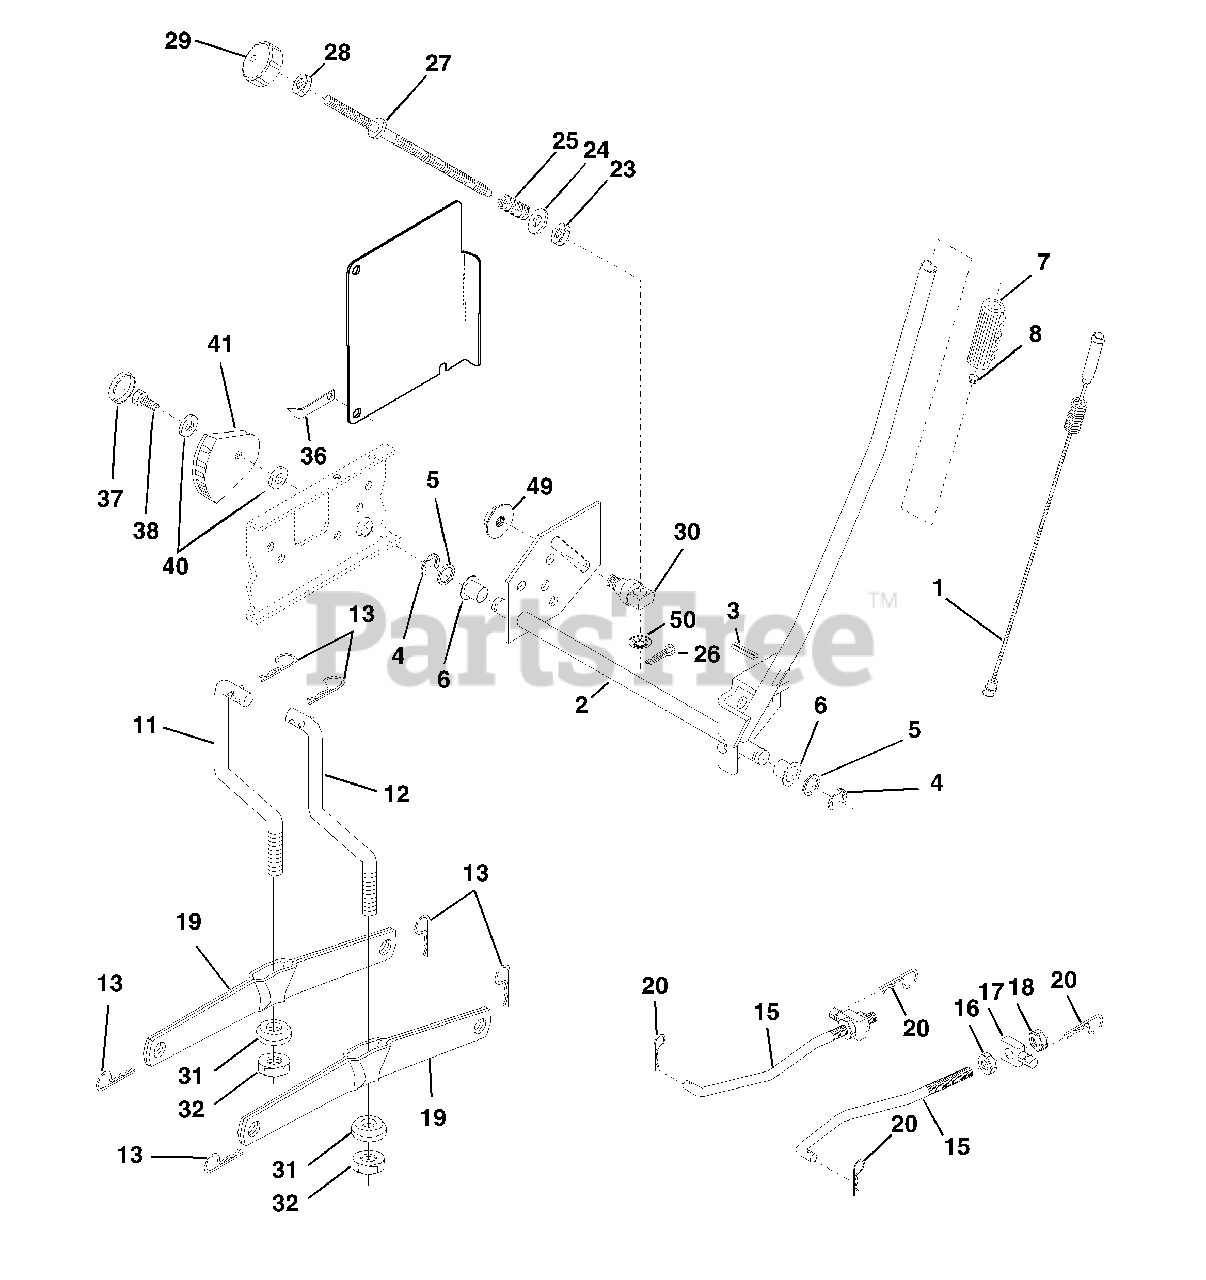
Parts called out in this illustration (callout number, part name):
1	Wire Asm Inner W/plunger
2	Shaft Asm Lift RH w/Inf
3	Pin Groove 1 500 Zinc
4	E Ring #5133-62
5	Washer 21/32 X 1 X 21 Ga
6	Bearing Nylon Blk 629 Id
7	Grip Handle Fluted Blk
8	Button Plunger Black
11	Link Lift LH Fixed Length
12	Link Lift RH Fixed Length
13	Retainer Spring
15	Link Front
16	Nut Jam Hex 1/2-13 Unc
17	Trunnion Blk Zinc
18	Nut Crownlock 1/2-13unc
19	Arm Suspension Rear
20	Retainer Spring
23	Nut Special
24	Washer 13/32 X 5/8 X 16 Ga
25	Spring 2-1/8"
26	Pin Cotter 3/32 X 1/2
27	Rod Adj Lift Zinc 7.49 Wrk Lg
28	Nut Hex Jam 3/8-16 Unc
29	Knob Inf 3/8-16 Unc Blk W/sym
30	Trunnion Infin Height
31	Bearing Pvt Lift Spherical
32	Nut Crownlock 3/8 - 24
36	Pointer Height Indicator
37	Plug Hole Blk 1.485/1.515 Dia.
38	Screw Thdrol 5/16-18 x 3/4
40	Washer 11/32 x 1-1/2 10 Ga.
41	Indicator Height STLT
49	Nut Hex Flange Lock
50	Nut Phos & Oil
